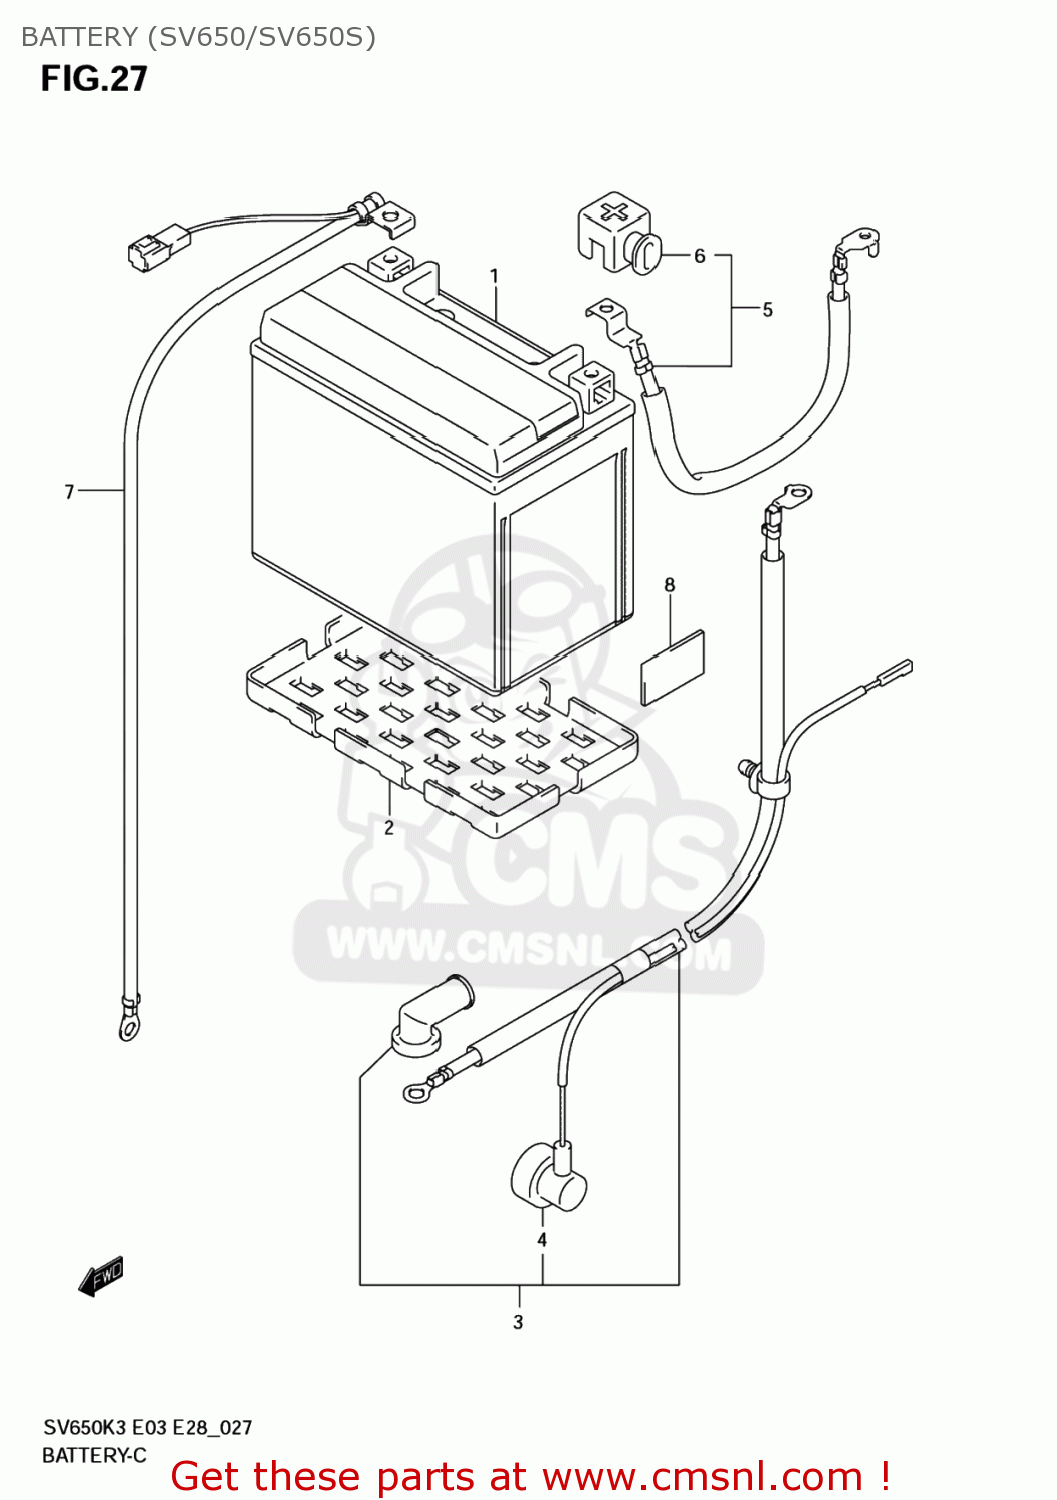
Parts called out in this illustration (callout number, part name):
1	BATTERY ASSY(YTX12-BS,12V10AH)
2	PROTECTOR,BATTERY
3	WIRE,STARTER MOTOR LEAD
4	CAP,OIL PRESSURE SWITCH
5	WIRE,BATTERY P
6	CAP,BATTERY PLUS
7	WIRE,BATTERY MINUS LEAD
8	PROTECTOR(30X50X3)
